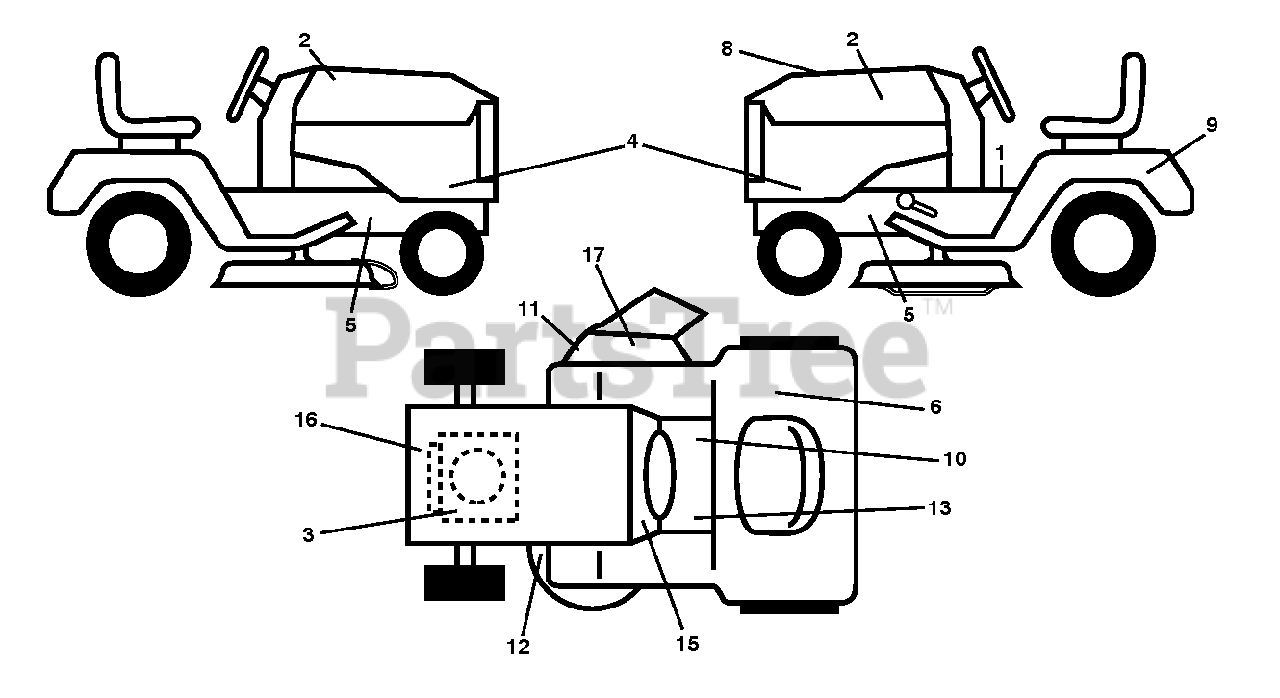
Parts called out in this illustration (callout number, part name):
1	DECAL.READ.OWN.MAN.SYMBOL.LT
2	DECAL.BADGE.170MM.TEXTLOGO.
3	DECAL.ENGINE.WARNING
4	DECAL.SDPNL.HUSQLT.TS142.HUSQV
5	DECAL.CHASSIS.HOT.MUFFLER
6	Decal, Certification 6MIL 100D
8	DECAL DECAL.RPL.BSM31.INTK.TLW
9	DECAL BTRY SYMBOLS
10	DECAL.PARKING.BRAKE.SADDLE.LT
11	DECAL.DFLCTR.WARNNG.CTFNGR.SYM
12	DECAL.V-BELT.SCH.42/46"MEC/ELE
13	DECAL.FNDR.SDLE.BRAKE.CLUTCH.6
15	DECAL.SNOWFLAKE.MS498.HUSQ
16	DECAL.ENG.BS.500CC.HS.382272
17	DECAL, DECK DEFLECTOR, WARNING
